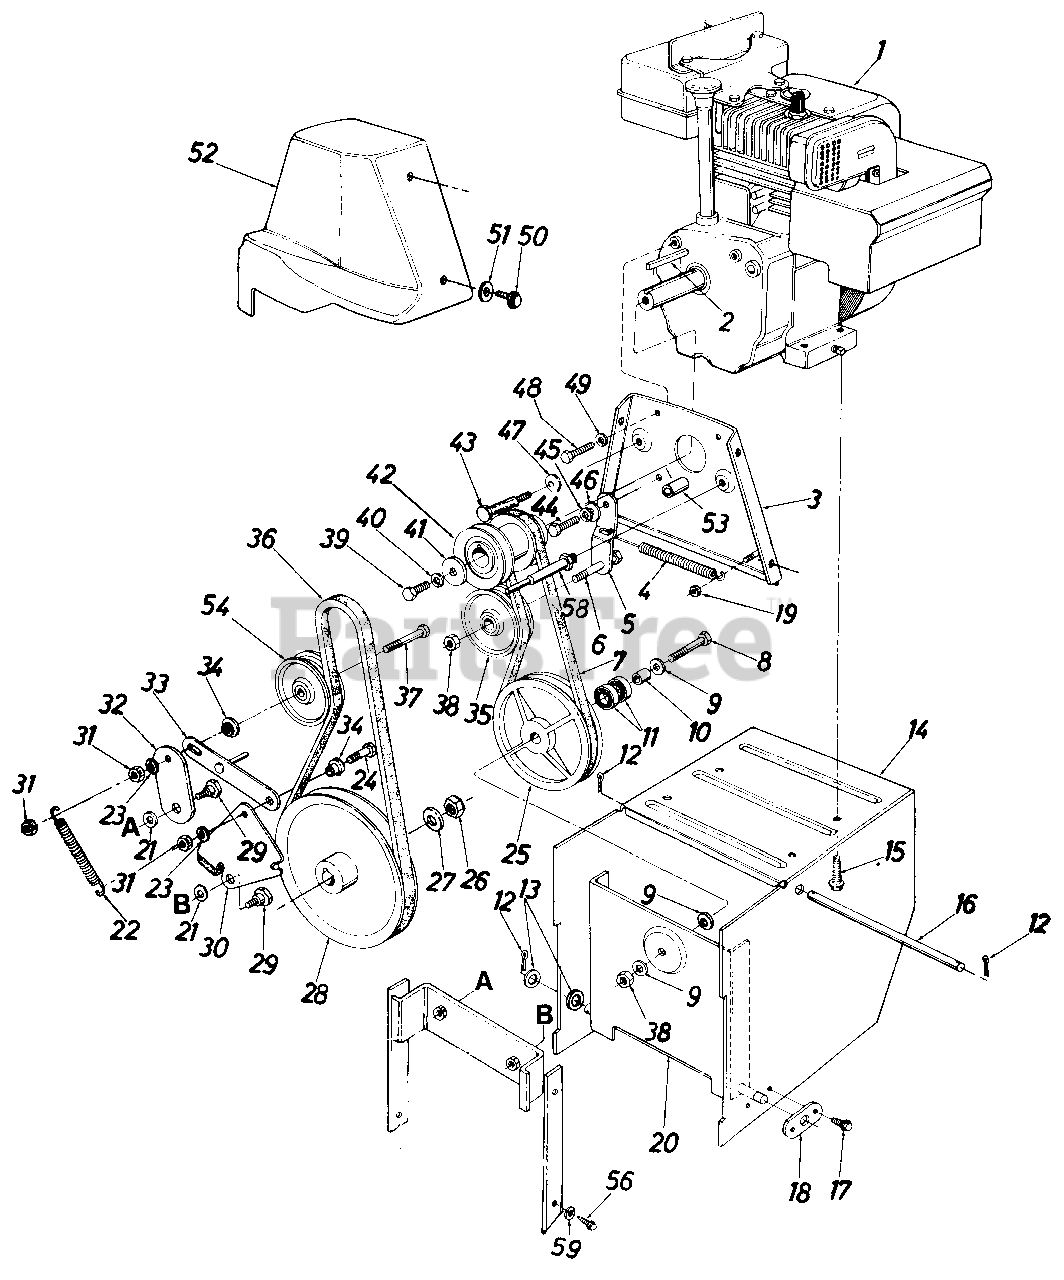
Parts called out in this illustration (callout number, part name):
1	Engine
2	Sq. Key 3/16" x 1.50" Lg.
3	Engine Plate Ass'y.
4	Extension Spring .50" O.D. x 3.97" Lg.
5	Drive Clutch Idler Brkt.
6	Hex Bolt 3/8-24 x 1.25" Lg.*
7	"V"-Belt
8	Hex Bolt 3/8-24 x 1.50" Lg.
9	Bell-Wash. .40" I.D. x .88" O.D. x .06
10	Spacer .38" I.D. x .62" O.D. x.75" Lg.
11	Ball Brg. .62" I.D. x 1.38" O.D. x .44
12	Cotter Pin 3132" Dia. x .75" Lg.
13	Fl-Wash. .53" I.D. x 1.00" O.D. x .125
14	Frame Ass'y.
15	Hex Wash. Hd. Self-Tap Scr. 3/8-16 x 1.25" Lg.
16	Shaft .50" Dia. x 9.50" Lg.
17	Hex Wash. Hd. Self-Tap Scr. 1/4-20 x .50" Lg.
18	Axle Bracket
19	Hex L-Nut 1/4-20 Thd.
20	Drive Pulley Support Brkt. Ass'y
21	Bell-Wash. .40" I.D. x 1.13" O.D
22	Extension Spring .56" O.D. x 4" Lg.
23	L-Wash. 318" I.D.*
24	Hex Scr. 3/8-16 x 1.25" Lg.
25	6.00" O.D. Drive Pulley Ass'y.
26	Hex Jam Cent. L-Nut 5/8-18 0 Thd.
27	Fl-Wash. .64" I.D. x.94" O.D. x .06
28	1/2" V-Pulley .625" I.D. x 7.50" O.D.
29	Shld. Bolt .625" Dia. x .170" Lg
30	Brake Bracket Ass'y.
31	Hex Ins. L-Nut 3/8-16 Thd.
32	Auger Clutch Idler Brkt.
33	Brake Linkage Ass'y.
34	Shld. Spacer .625" I.D.
35	Fl-ldler Pulley 2.25" O.D.
36	"V"-Belt
37	Hex Bolt 3/8-16 x 2" Lg.*
38	Hex Ins. Jam L-Nut 3/8-24 Thd.
39	Hex Bolt 3/8-24 x 1.50" Lg.
40	L-Wash. 3/8" I.D.*
41	Bell-Wash. .40" I.D. x 1.25" O.D.
42	Double Groove Engine Pulley
43	Shld. Scr. .498" x 3.0" Lg.
44	Hex Bolt 5/16-24 x 1.00" Lg.
45	L-Wash. 5/16" I.D.*
46	Shld. Spacer .27" Lg.
47	Bell-Wash. .40" I.D. x .88" x .06
48	Hex Bolt 5/16-24 x .62" Lg.
49	L-Wash. 5/16" I.D.*
50	Hex Wash. Hd. Self-Tap Scr. 1/4-20 x .50" Lg.
51	Fl-Wash. .28" I.D. x .75" O.D. x .06
53	Spacer
54	Fl-ldler Pulley 2.75" O.D.
56	Hex Wash. Hd. Self-Tap Scr. 3/8-16 x .75" Lg.
58	Stud 3/8-16 x 3.37" Lg.
59	L-Wash. 3/8" I.D.-H.D.
